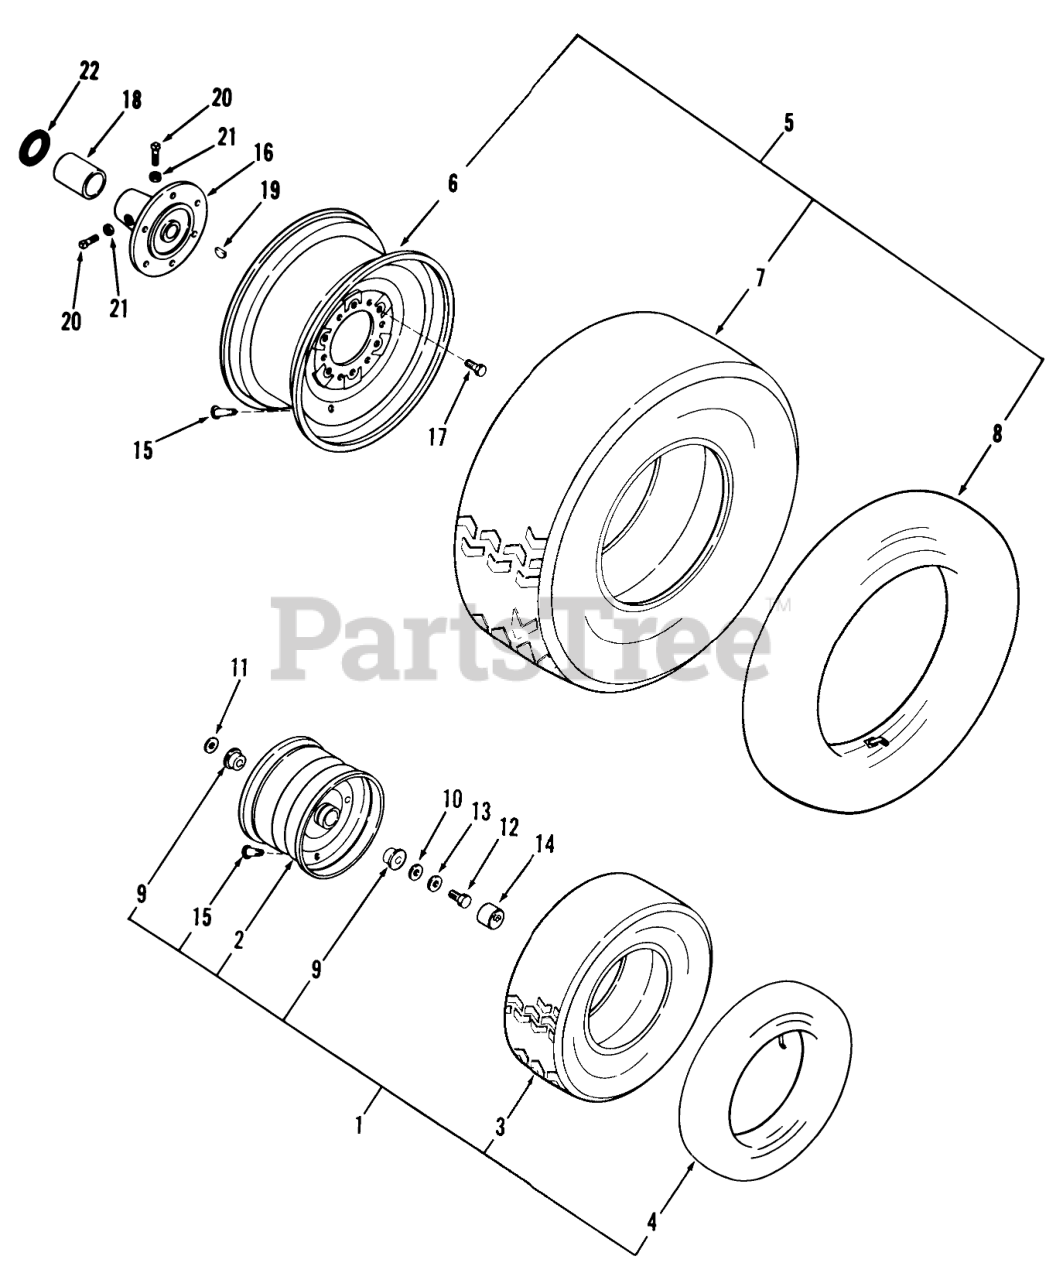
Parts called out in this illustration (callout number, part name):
1	ASSY-WHEEL
2	Wheel
3	Tire 18 X 850-8 Staight Rib
4	TUBE-TIRE
5	Rear Wheel & Tire Cleat (Right Side)
5	Rear Wheel & Tire Cleat (Left Side)
5	Rear Wheel & Tire Turf
6	Wheel 12 x 10.5 PC
7	Tire, Extra Width Traction
7	Tire, Extra Width Cleat
8	Yoke
9	BEARING WHEEL
11	Washer
12	Bolt
13	WASHER
14	HUBCAP
15	VALVE
16	REAR HUB R
17	LUG BOLT WHEEL 7/162
18	Axle Cover Tube
19	WOODRUFF KEY
20	SS-SQ HD3/8-16X1 1/2
21	Nut
22	WASHER-THRUST
